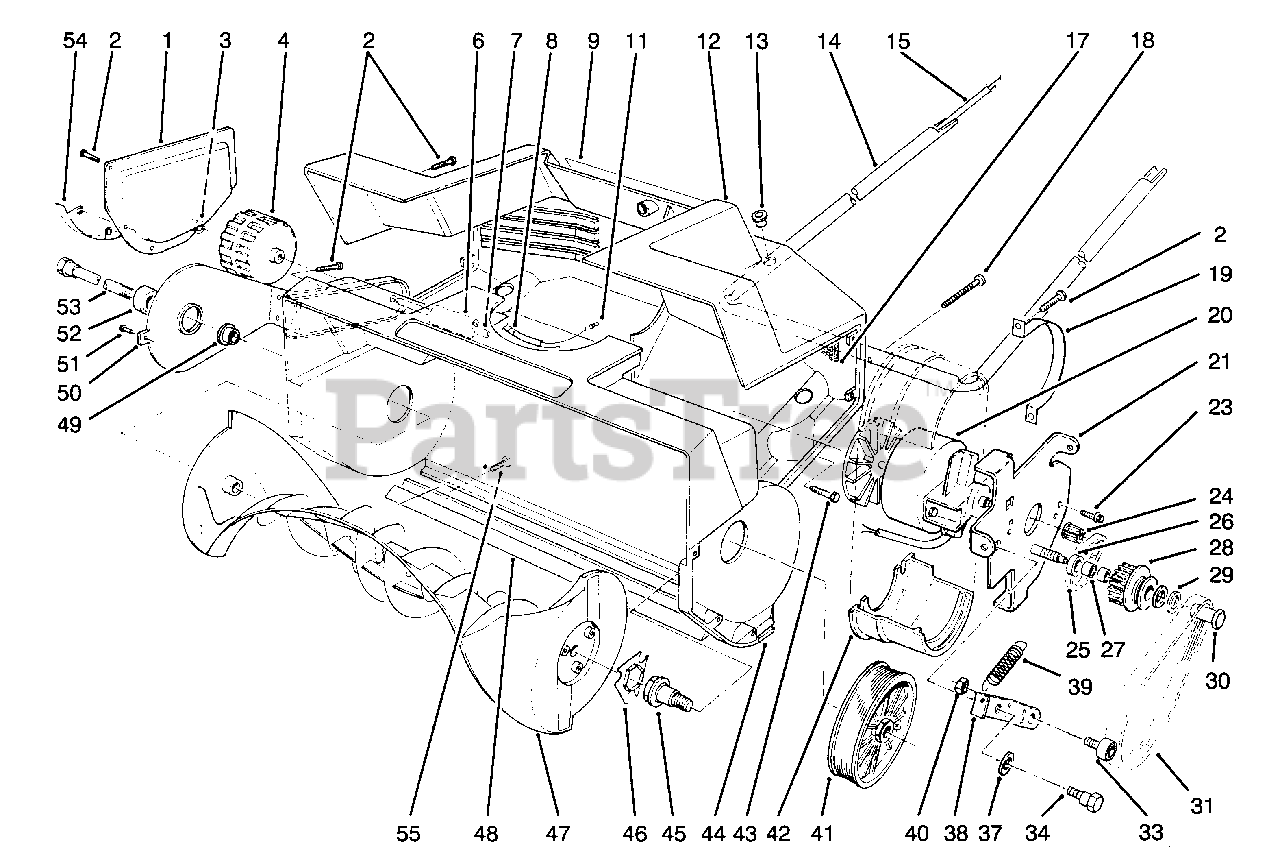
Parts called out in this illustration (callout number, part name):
1	Plate-Side
2	Screw-Pan Hd.
3	Push Nut
6	Sleeve-Axle
7	Shaft-Axle
8	Relief-Strain
9	Decal-Danger
11	Connector
12	Shroud-Housing
14	Tube-Lower Handle
15	Wire Harness
17	Filter-Foam
18	Screw-Pan Hd.
19	Strap-Motor
21	Motor Plate Assembly
23	Screw-Hex. Washer Hd.
24	Pulley-Driver
25	Belt-Timing
27	Bearing-Needle
28	Pulley Assembly-Idler (Incl. Ref. #27)
29	Washer-Thrust
30	Bolt-Idler
31	Belt-Drive
33	Bearing Assembly (Incl. Ref. #40)
34	Screw-Shoulder
38	Bracket-Idler
40	Nut-Lock
41	Pulley-Driven
42	Clamp-Motor Bracket
43	Screw-Hex. Hd.
44	Housing-Rotor
45	Shaft-Rotor Driver
46	Coupler-Rotor
50	Bracket-Wheel (Incl. Ref.#52)
51	Rivet-Pop
52	Bearing-Ball
53	Shaft-Rotor
54	Skid-Housing
55	Screw-Pan Hd.
